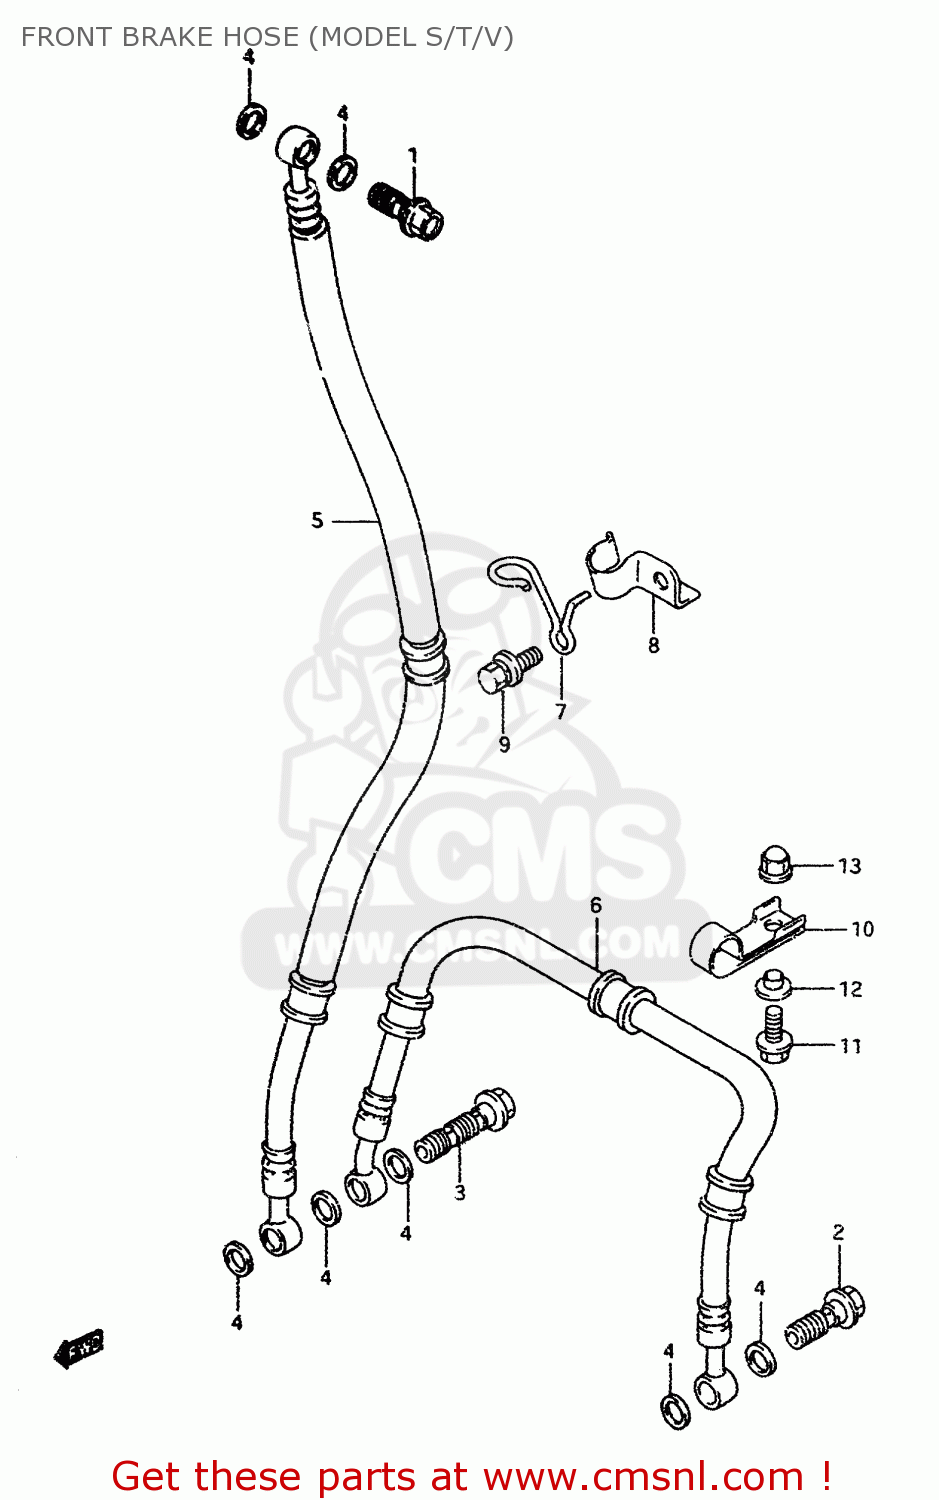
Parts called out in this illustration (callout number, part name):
1	BOLT UNION
2	BOLT UNION
3	BOLT UNION
4	WASHER(10X15X1.5)
5	HOSE COMP,FRONT BRAKE
6	HOSE,FR BRAKE NO.2
7	GUIDE,FR BRAKE HOSE
8	CLAMP,FR BRAKE HOSE UPR
9	BOLT
10	CLAMP,FR BRAKE HOSE NO.2
11	BOLT
12	WASHER
13	NUT
